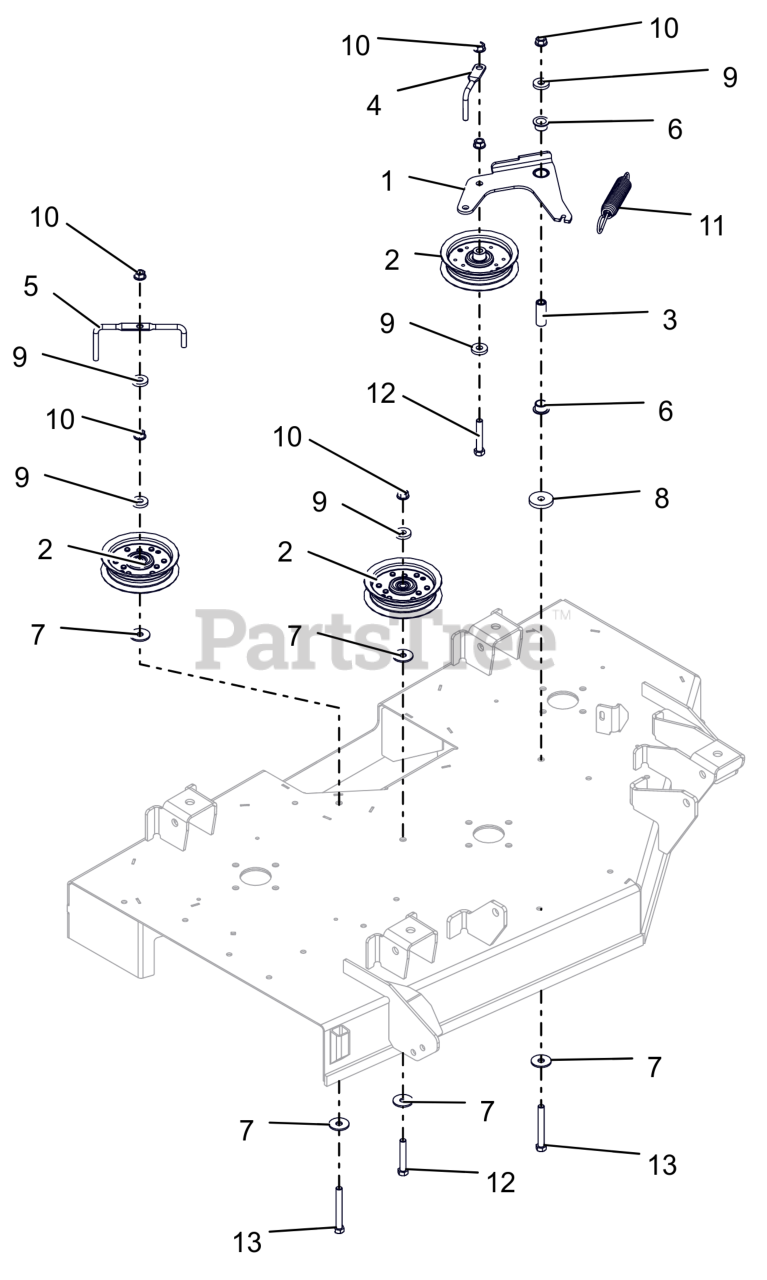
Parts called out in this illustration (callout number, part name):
1	WLDMT, IDLER ARM-42"
2	ASM, IDLER 4"
3	SPACER, .375IDX.625ODX1.66 PM
4	WIREFORM, BELT FINGER
5	WIREFORM, BELT FINGER
6	BSHG-FLG, .625X.750X.500X1.00
7	WSHR FL STL .406X1.25X.10ZC120
8	WSHR, FLT .406X1.50X.245 ZCC
9	WSHR, FLT .406X1.00X.188 ZCC
10	NUT-LK-CTR-FLG .375-16 GF ZCC
11	SG-TENS .135X.98X6.0 WLD 62
12	BLT,HEX .38-16X2.25 G5 ZCC
13	BLT, HEX .38-16X3.00F G5 ZCC
